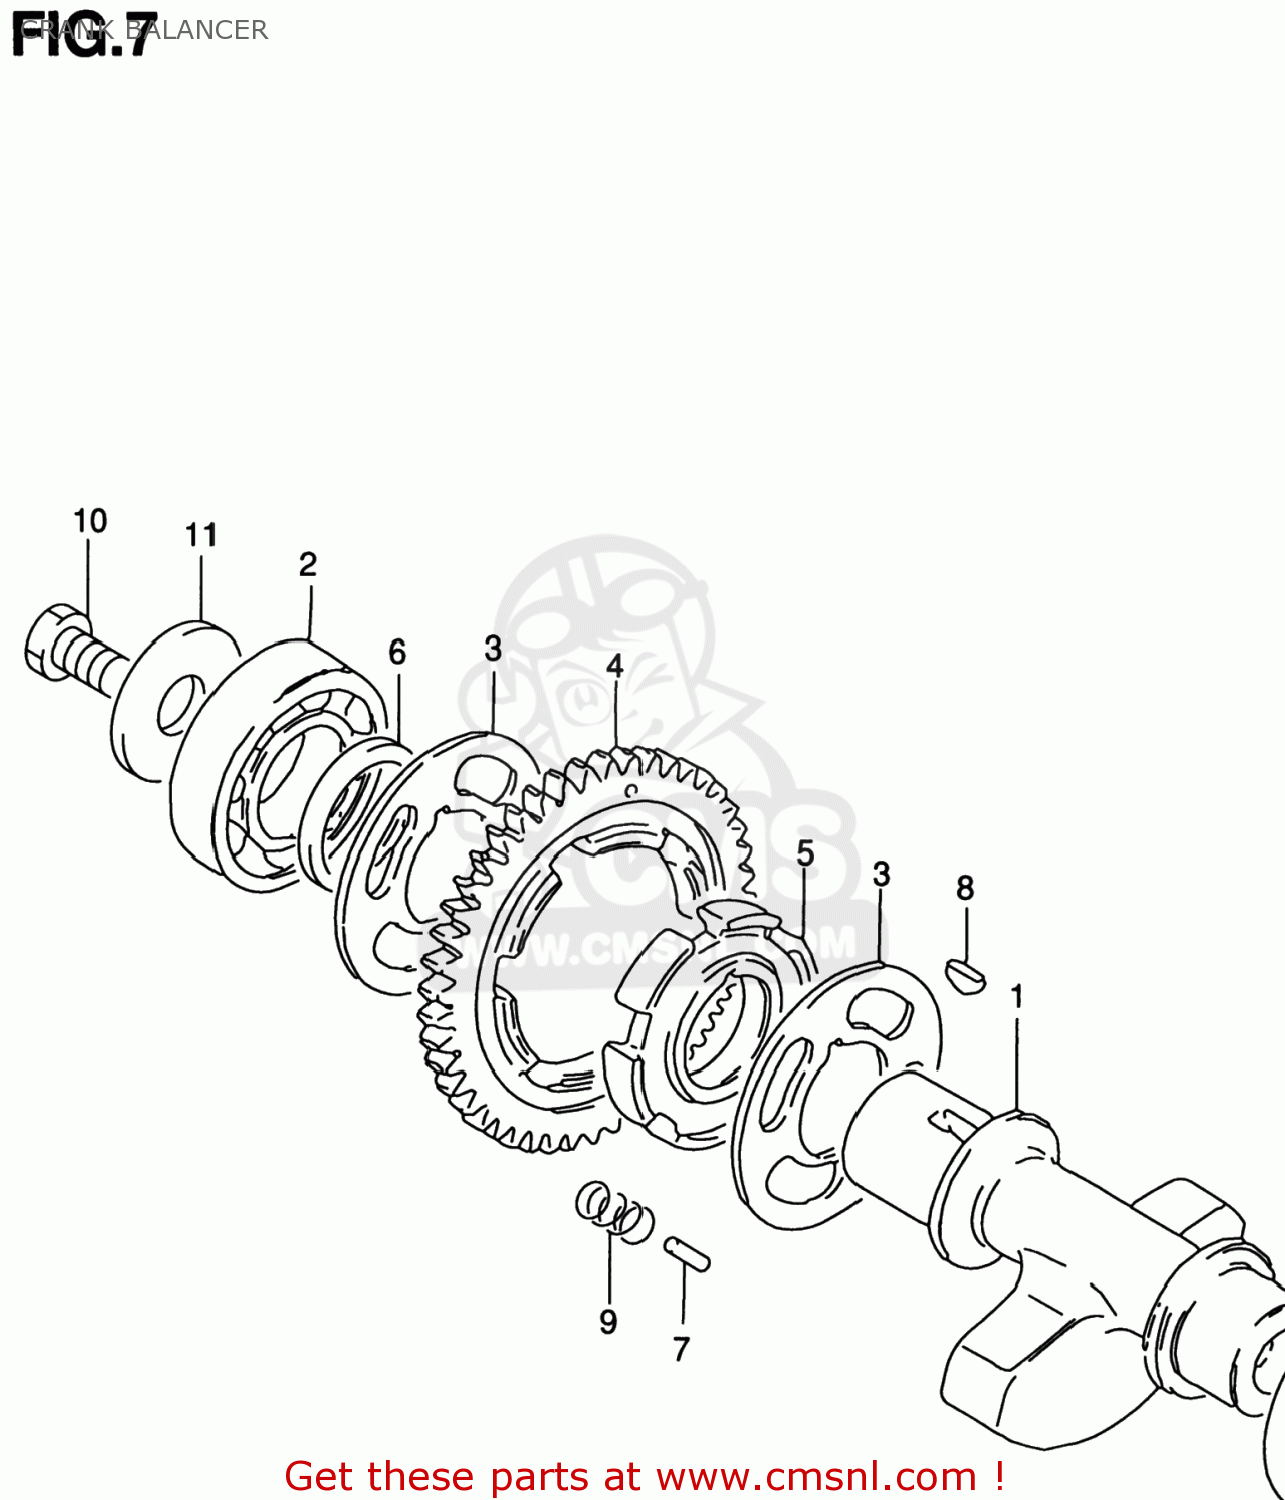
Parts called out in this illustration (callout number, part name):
1	SHAFT,CRANK BALANCER
2	BEARING(25X62X17)
3	WASHER
4	GEAR,CRANK BAL DRIVEN(NT:46)
5	RACE,CRK BAL DRIVEN GR INNER
6	SHIM(25X36X0.5)
7	PIN(4.5X9.5)
8	KEY
9	SPRING
10	Bolt
11	WASHER(12X40X2.5)
